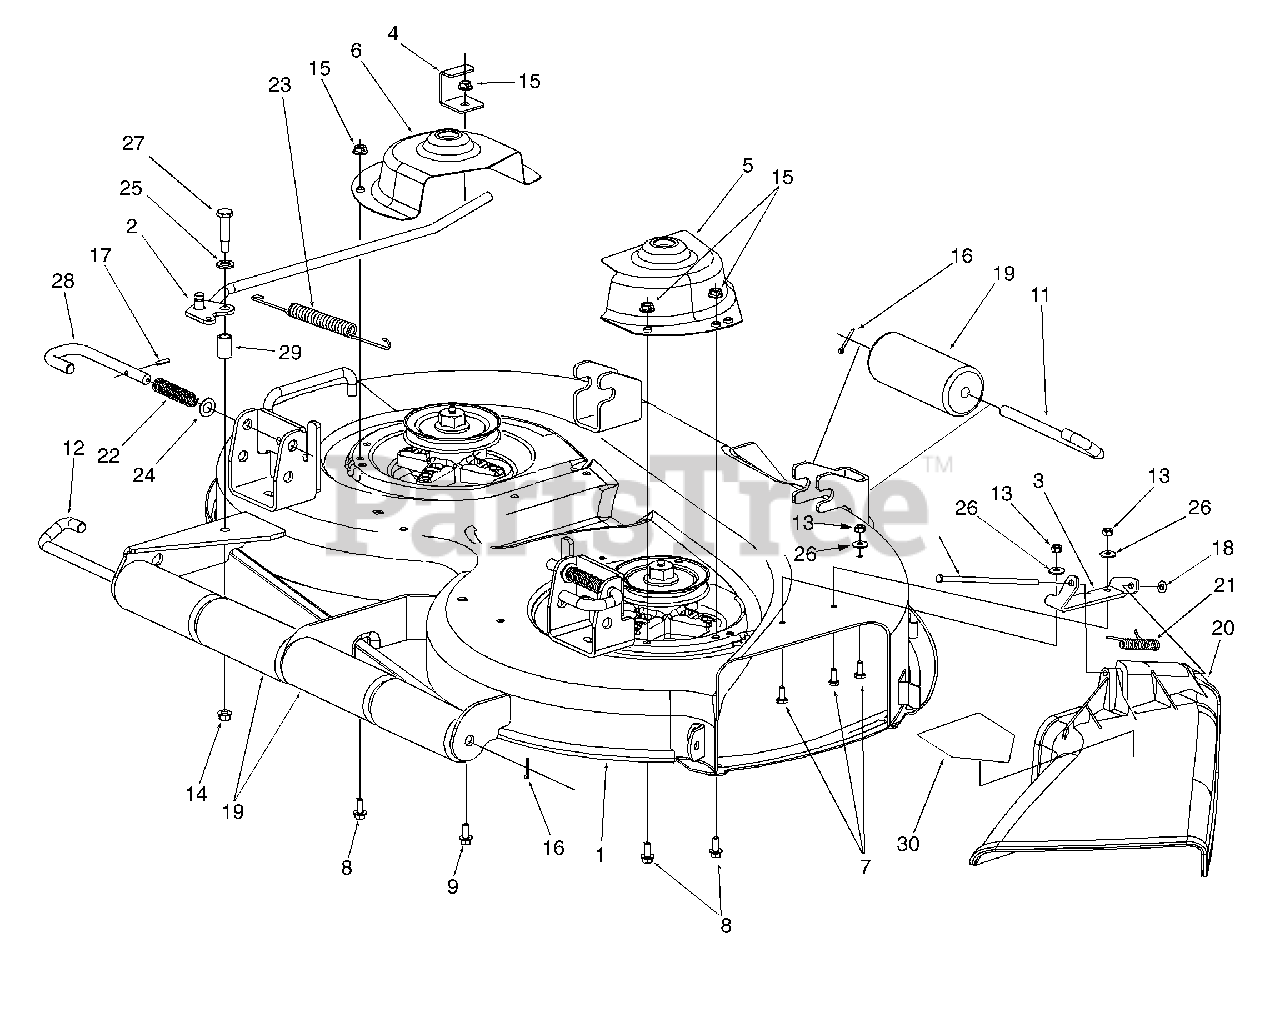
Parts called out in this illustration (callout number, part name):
2	Rod Ass'y, Engagement
3	Bracket, Hinge Mounting
7	Screw, Hex Cap, 1/4-20 x .62
8	Screw, Hex Wash Hd TT Tapp 5/16-18 x .75
9	Screw, Hex Cap 5/16-18 x .75 GR5
11	Pin, Roller, 1/2 x 7.31
12	Pin, 42" Deck Roller
13	Nut, Hex, 1/4-20
14	Nut, Hex Flange Lock, 3/8-16
15	Nut, Hex Flange Lock, 5/16-18
16	Pin, Cotter, 1/8 x 1.0
17	Pin, Spirol, 3/16 x 3/4
18	Cap, Speed Nut
20	Deflector Ass'y, Chute
21	Spring, Torsion
22	Spring, Compression
23	Spring, Extension
24	Washer, Flat, .536 x .93 x ,05
25	Washer, Flat, .531 x .93 x .90
26	Washer, Bell, .265 x .75 x .062
27	Bolt, Shoulder, .498 x 1.45:3/8-16
28	Pin, Mower Support
29	Spacer, .550 x .750 x .965
30	Graphic, Danger Cut Finger
